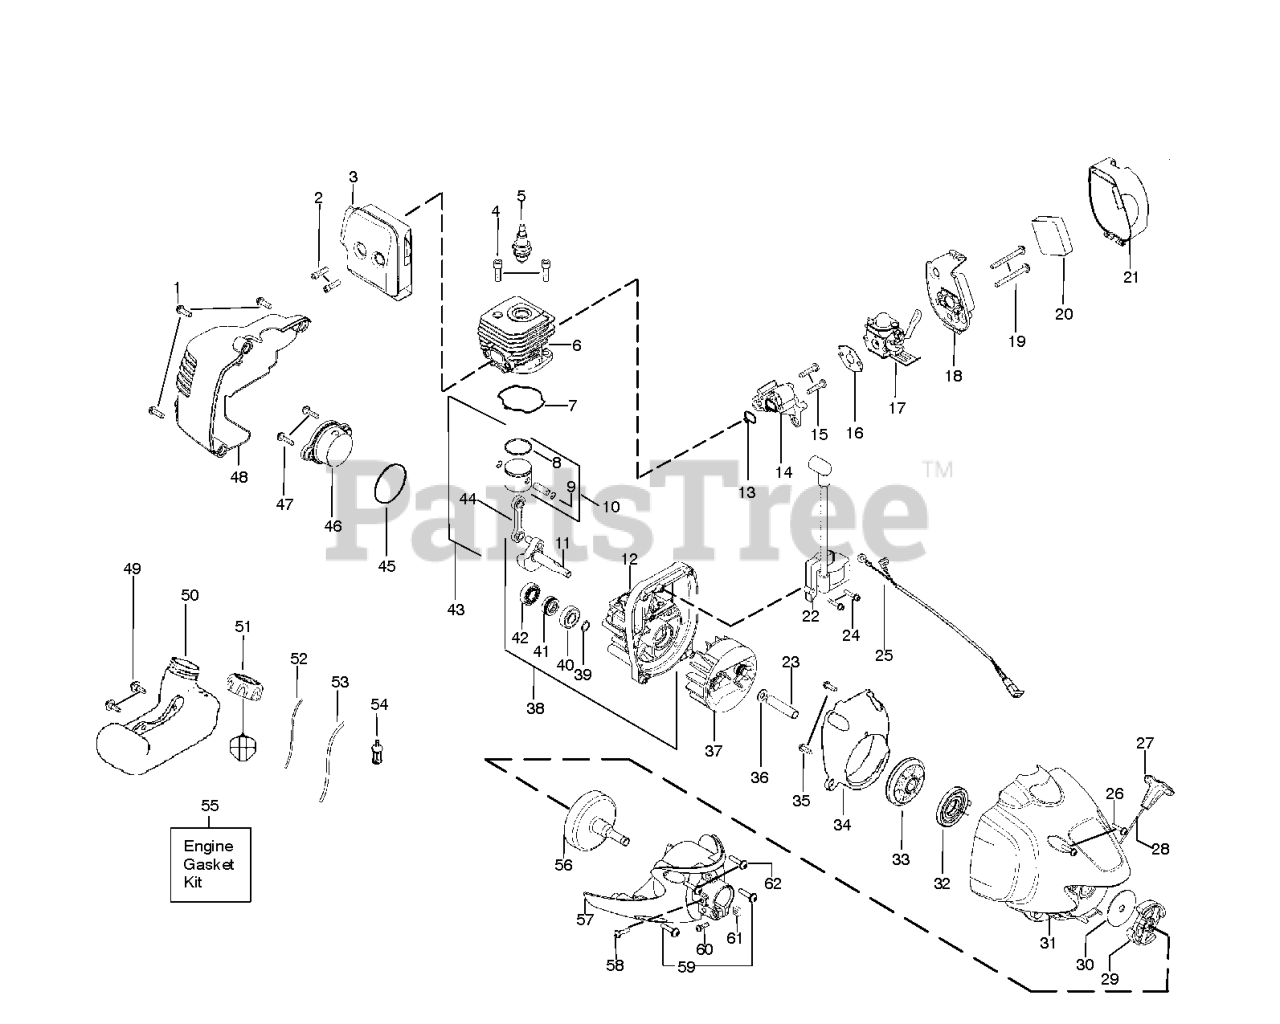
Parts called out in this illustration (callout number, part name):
1	Screw - Line Limiter
2	Bolt - Muffler
4	Screw - Cylinder
5	BPMR7A NGK SPARK PLUG
6	Cylinder - Machined (25cc)
7	Seal-Cyl/Carb. (kit)
9	Retainer - Wrist Pin (PRO150 Only)
10	Kit - Piston
11	ASSY CRANKSHAFT
12	Assy - Crankcase
13	Seal-Cyl/Carb. (kit)
14	ADAPTOR CARBURETOR
15	Screw .20 x 32
16	Seal-Cyl/Carb. (kit)
17	Kit-Carb. Zama (C1U-W18)
18	BASE AIR BOX PP GOLD
21	COVER AIR BOX FE
22	%MODULE IGNITION
23	Spacer-Flywheel
24	Screw-Ignition Module
25	Assy-Lead Wire New Style (type 2)
26	Screw-Fan Housing/Shroud
27	HANDLE STARTER BLK
28	Kit - Rope
29	ASSEMBLY CLUTCH
30	Clutch Washer-Models HP22T, HP30SB
31	ASSY FAN HSG BLACK
32	SPRING STARTER SA
33	Kit - Starter Pulley
34	BAFFLE FAN
35	Screw - Line Limiter
36	Washer-Clutch Flat
37	ASSY FLYWHEEL
38	ASSY CRANKCASE & CRANKSHAFT
39	Ring - Crankshaft Retainer
40	Bearing - Outer
41	Seal - Crankshaft
42	Bearing - Inner
43	Kit - Piston and Rod
44	Kit-Connecting Rod Assy.
45	Seal-Cyl/Carb. (kit)
46	Assy-Plug (incl.45)
47	Screw-Fan Housing/Shroud
48	SHROUD REAR BLACK
49	Screw - Fuel Tank Retainer
50	ASSY FUEL TANK
51	FUEL CAP ASSY LOW PERMEATION
52	Line Kit(Bulk 8148) - Model 1400 G.TRIMMER-T2 1400T-T1
53	Kit-Line Purge/Tank (large line)
54	ASSY FUEL PICKUP PRE FLUSHED
55	Seal-Cyl/Carb. (kit)
56	ASSY CLUTCH DRUM W/ADPT
57	Assy-Clutch Cover
58	Screw-Align
59	SCREW-10-24 X 1" (TAP.)
60	SCREW 12-24 X 5/8
61	NUT SQUARE 12-24
62	Screw-Shroud/Blower Hsg.
